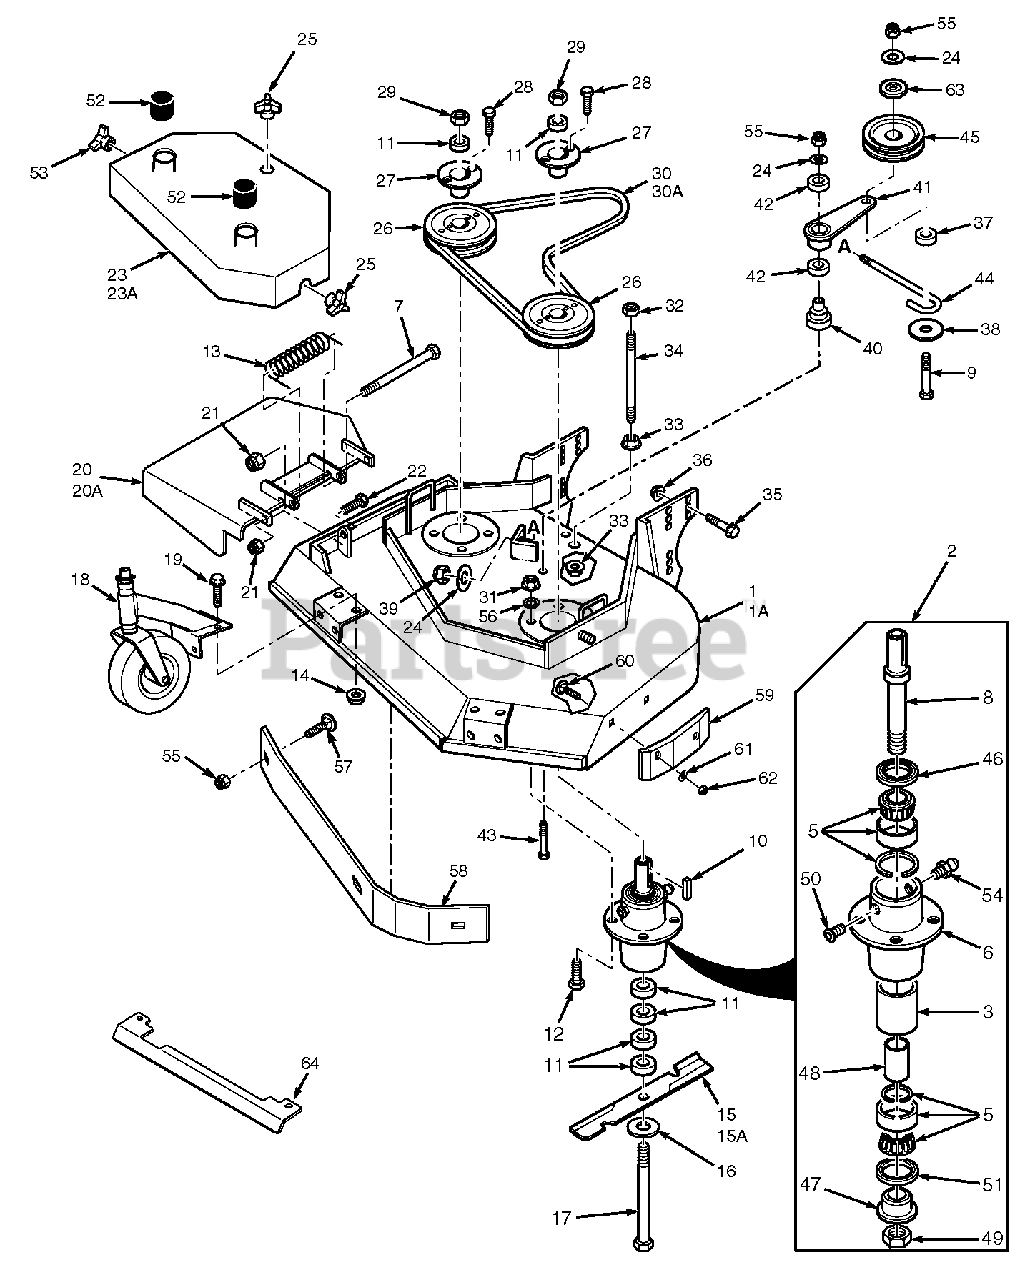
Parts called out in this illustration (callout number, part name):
1	Cutter Deck w/Decals
2	Cutter Spindle Assembly
3	Spacer, Outside
5	Bearing, Tapered
6	Spindle Housing
7	Bolt, 5/16-18 x 4-3/4'
8	Spindle Shaft
9	Bolt, 3/8-16 x 3-3/4' Hex Head
10	Key, 1/4 x 1/4 x 2'
11	Spacer, Cutter Blade - Small
12	Bolt, 5/16-18 x 1-1/2' Hex Head
13	Spring, Chute Return
14	Nut 5/16-18 Serrated Flange
15	Cutter Blade, 18'
15A	Cutter Blade, 18 Hi-Lift
16	Flatwasher, 5/8 W
17	Hex Hd. Bolt, 5/8-11 x 9-1/2'
18	Caster Assembly
19	Cpscrw,5/16-18 x 3/4' Ser.Flg. Hex Head
20	Discharge Chute
21	Hex Nut, 5/16-18 Elastic Stop
22	Hex Hd Bolt, 5/16-18 x 1'
23	Belt Cover Assy
23A	Belt Cover Assy
24	Flat Washer, 3/8' Special
25	Wing Nut, 3/8-16
26	Pulley
27	Tapered Hub
28	Hex Hd. Bolt, 1/4-20 x 1'
29	Hex Nut, 5/8-11
30	Belt, Blade Drive
31	Elastic Stop Nut, 5/16-18
32	Hex Nut, 3/8-16 Center Locknut
33	Nut, 3/8-16 Serrated Flange
34	Support, Belt Cover
35	Cpscrw, 1/2-13 x 1'Ser.Flg. HH
36	Nut, 1/2-13 Flange Elastic Stop
37	Spacer, J-Hook
38	Flatwasher, 3/8 x 1-1/2 x 16 GA
39	Elastic Stop Nut, 3/8-16
40	Idler Pivot
41	Idler Arm Assy.
42	Bearing
43	Cpscrw, 3/8-16 x 3-1/4' Hex Head
44	J-Hook
45	Idler Pulley, Belt Clutch
46	Seal, Cutter Spindle
47	Spindle Bushing
48	Spacer, Inside
49	Nut,1.06-18
50	Relief Fitting, Cutter Spindle
51	Seal, Cutter Spindle
52	Cap, Spindle
53	Wing Nut, 3/8-16 (Small) RH side
54	Grease Fitting
55	Nut, Hex Elastic Stop 3/8-16
56	Lock Washer, 5/16'
57	Bolt, Carriage 3/8-16 x 1'
58	Baffle Weldment
59	Pad, Deck Wear
60	Bolt, Carriage 5/16-18 x 3/4'
61	Flatwasher, 5/16'
62	Hex Nut, 5/16-18 Center Locknut
63	Dust Shield
64	Heatshield
